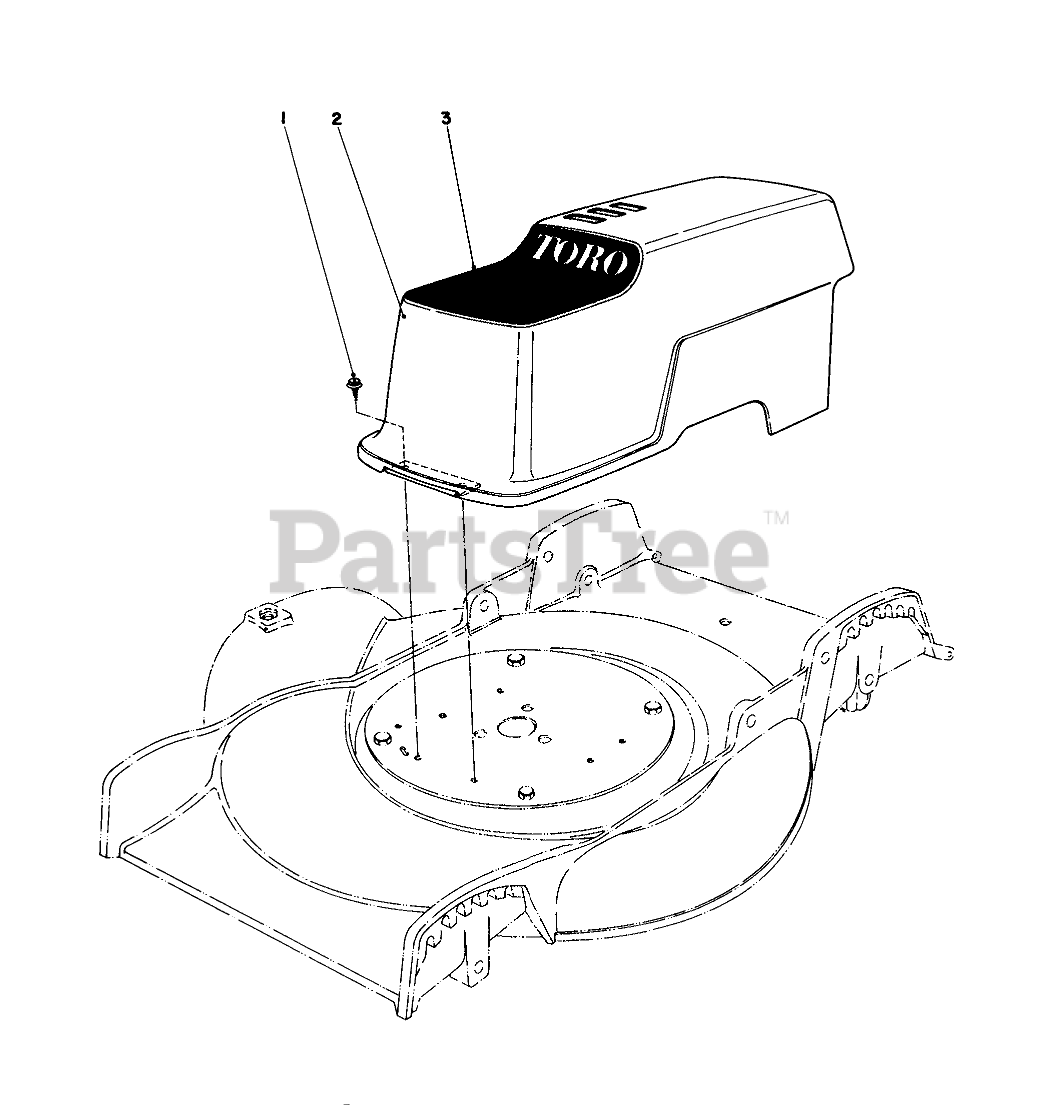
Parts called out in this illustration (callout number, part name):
1	SCREW-HWHTF
2	Shroud
3	Decal Shroud
